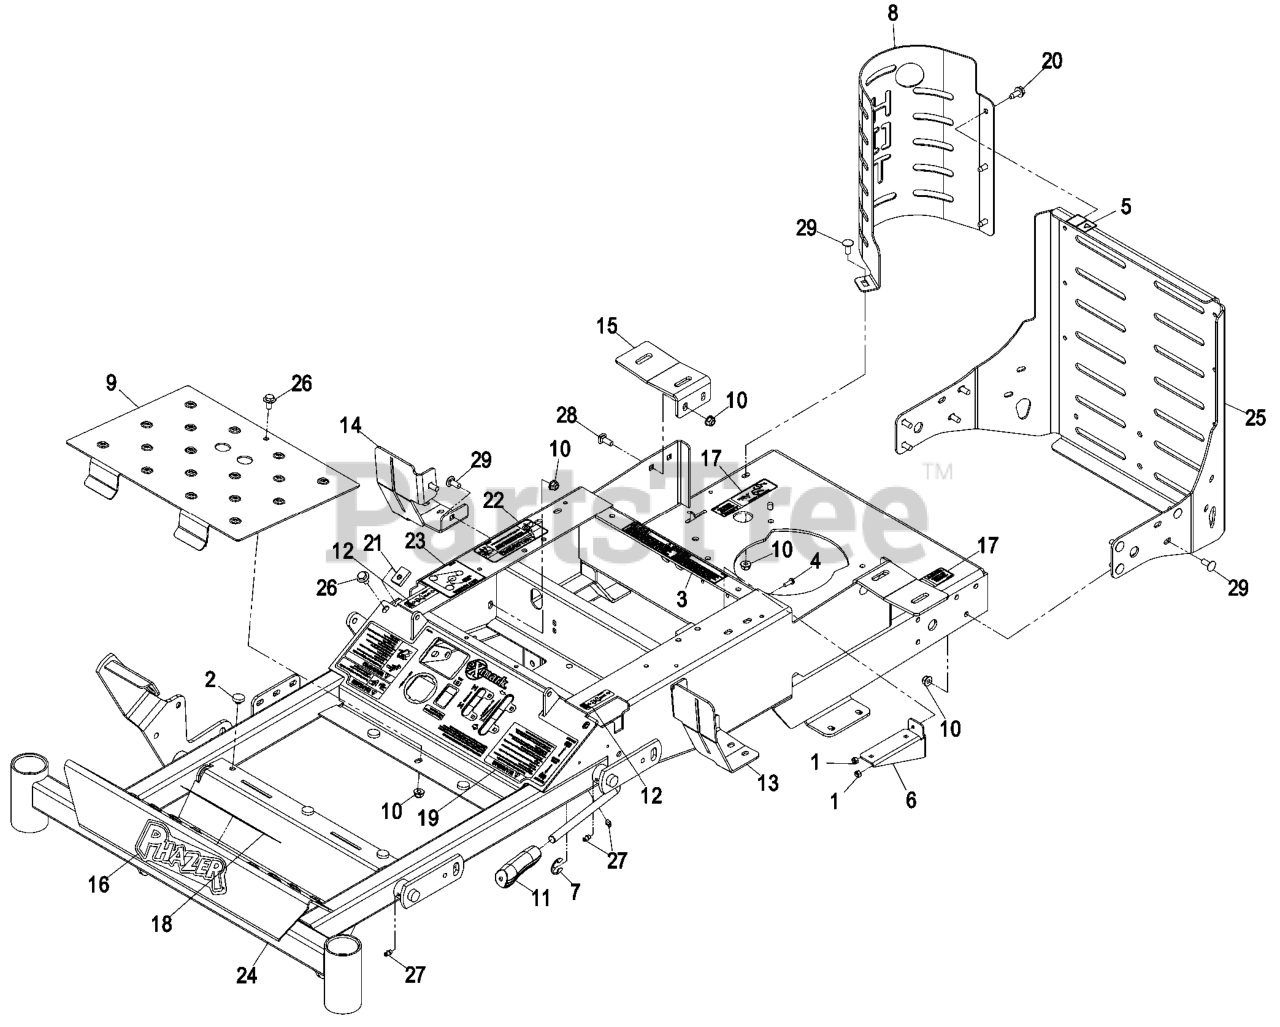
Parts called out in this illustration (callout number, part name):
1	NUT-LOCK, NI
3	DECAL-BATTERY
4	SCREW-PPH
5	DECAL-SURFACE, HOT
6	BRACKET-FUSEBLOCK
8	GUARD-MUFFLER
10	NUT-HF, NI
11	GRIP-LEVER, BRAKE
12	DECAL-CONTROL, MOTION
13	MOUNT-TANK, FUEL (LH)
14	MOUNT-TANK, FUEL (RH)
15	BRACKET-FUEL TANK, REAR
16	DECAL,PHAZER
17	DECAL,ZT DUMP
18	DECAL-SLOPE, DANGER
19	DECAL,CONSOLE
20	Screw-HWH 5/16-18 X 3/4 Tf
21	STOP-MOTION
22	DECAL-DEVICES, ROTATING
23	DECAL,BELT ROUTING
24	ASM,FRAME WITH DECALS
25	REAR GUARD ASM
26	SCREW-HHF
27	FITTING-GREASE
28	SCREW-CARR
29	SCREW-CARR
